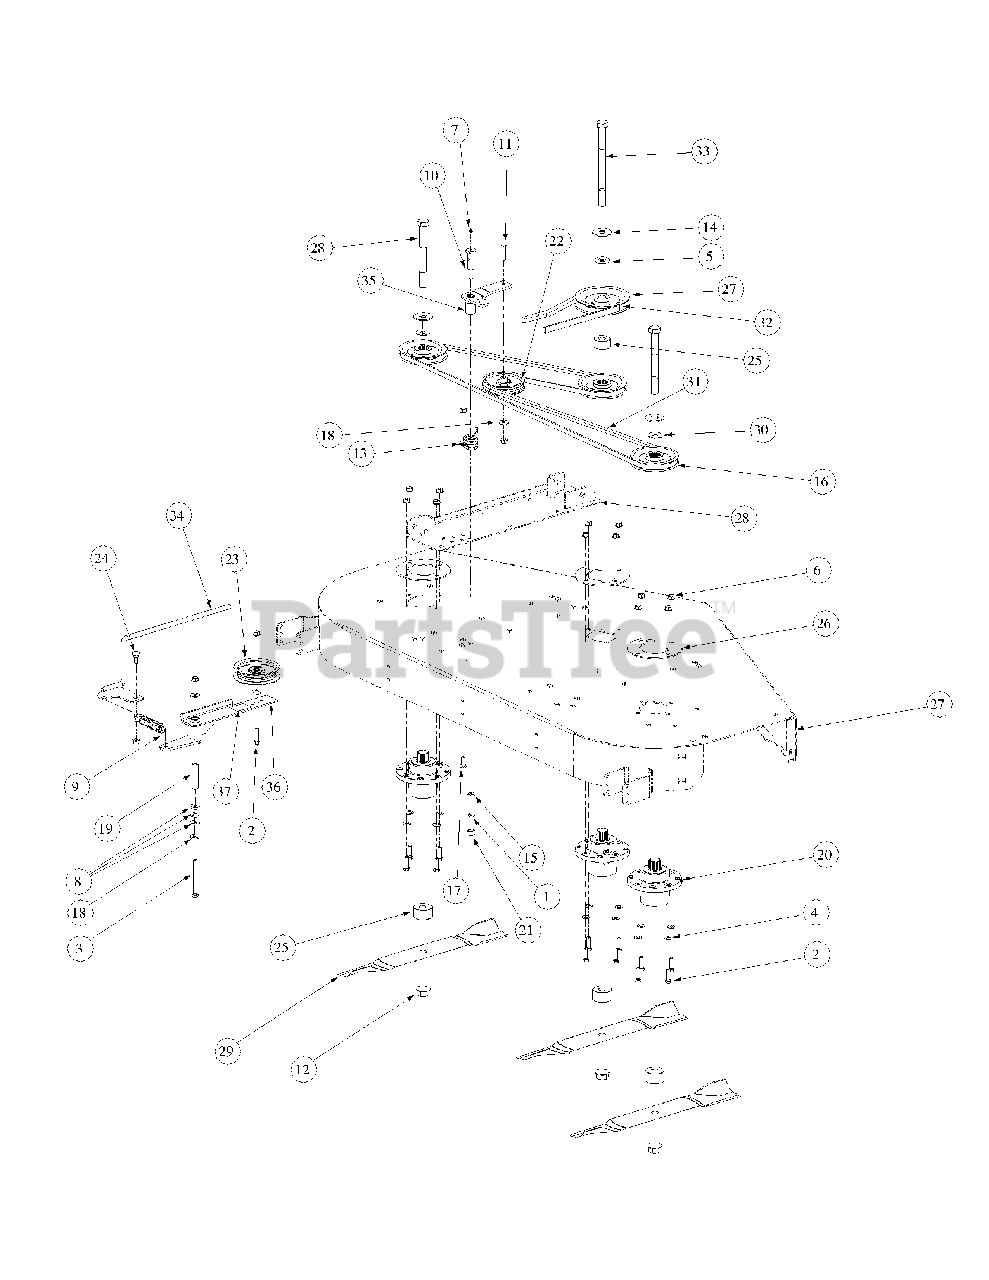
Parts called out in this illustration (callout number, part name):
1	Lock Washer, 7/16
2	Hex Cap Screw, 3/8-16 x 1-1/4
3	Hex Cap Screw, 3/8-16, 4.00
4	Flat Washer, 3/8
5	Caster Spacer
6	Flange Lock Hex Nut, 3/8-16
7	Grease Fitting, 1/4-28 x 3/16
8	Idler Washer
9	Extension Spring, 1.0 x OD x 5.125
10	Shoulder Screw, 7/16-14
11	Hex Carriage Screw, 3/8-16, 1.75
12	Flange Hex Nut, 3/4-16
13	Torsion Idler Spring
14	Flat Washer, .781 ID 2.00 OD, .105
15	Flat Washer, .469 ID, .875 OD, .105
16	V-Pulley, 5.00 OD
17	Carriage Bolt, 3/8-16 x 1
18	Flat Washer, .406 ID, 1.0 OD, .105
19	Spacer, .39 ID x .625 OD x 2.75
20	Aluminum Spindle Assembly
21	Hex Nut, 7/16-14
22	Flat Pulley
23	Idler Pulley, 4.06 OD
24	Shoulder Screw, .50 x .27 Lg., 3/8-16
25	Spacer, .760 ID x 2.00 OD x 1.1
26	Aluminum Spindle Support Plate
27	V-Pulley, 5.774 OD
28	Hex Cap Screw, 3/4-16, 7.00
29	Hi-Lift Blade, 21.0, 0.756 ID
30	Spacer .812 ID x .268 LG
31	V-Belt, A Section x 122.3
32	V-Belt, B Section x 91.2
33	Hex Cap Screw, 3/4-16, 9.00
34	Spring Tension Rod Assembly
35	Idler Arm Assembly, Deck Spindle
36	Idler Arm Assembly, Flat Top Bearing
36	Bearing Sleeve
37	Decal, Idler Location
